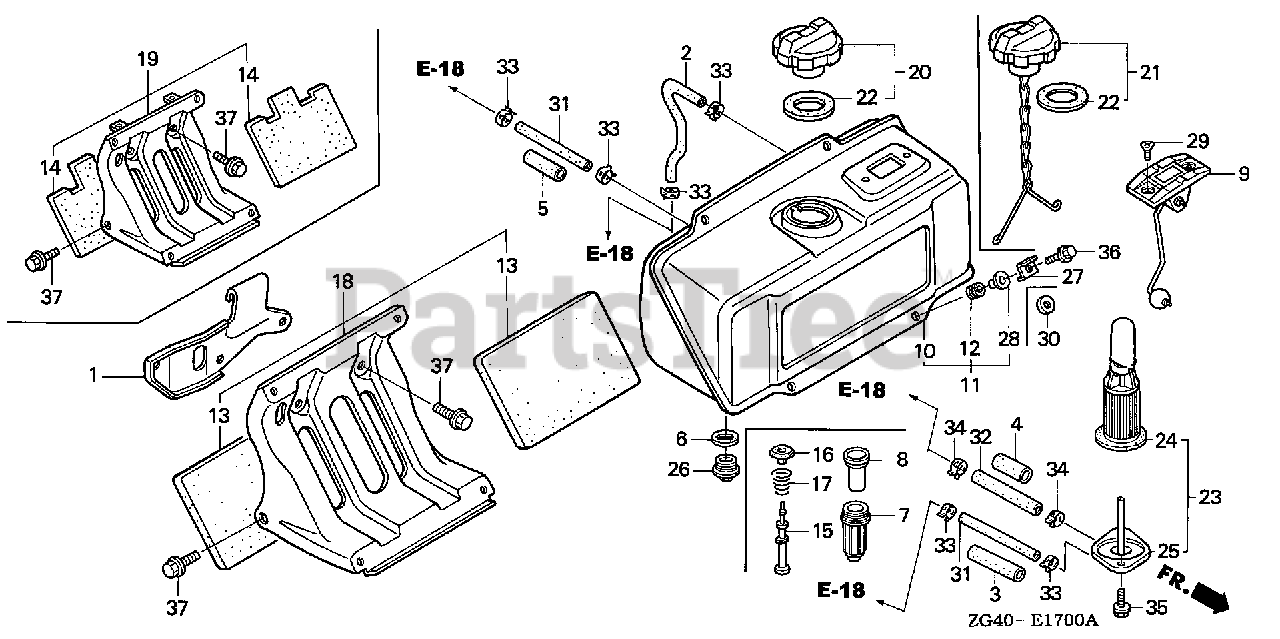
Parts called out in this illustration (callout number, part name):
1	HANGER, ENGINE
2	TUBE, FUEL
3	RUBBER, SUPPORTER (9X48)
4	RUBBER, SUPPORTER (B)
5	RUBBER, SUPPORTER (9X30)
9	GAUGE ASSY., FUEL
10	TANK, FUEL *R280* (GAUGE) (POWER RED)
13	SEAT, TANK STAY
18	STAY, FUEL TANK
20	CAP, FUEL FILLER
22	GASKET, FUEL FILLER CAP (39X58X3)
23	FILTER ASSY., FUEL
25	BODY, STRAINER
26	BOLT, DRAIN
27	WASHER, SPECIAL (6MM)
29	SCREW, FLAT (5X10)
31	BULK HOSE, FUEL (4.5X3000) (4.5X100)
32	BULK HOSE, FUEL (8X1000) (8X90)
33	CLAMP, TUBE (D8)
34	CLAMP, TUBE (D12.5)
35	BOLT, FLANGE (6X12)
36	BOLT, FLANGE (6X14)
37	BOLT, FLANGE (8X22)
